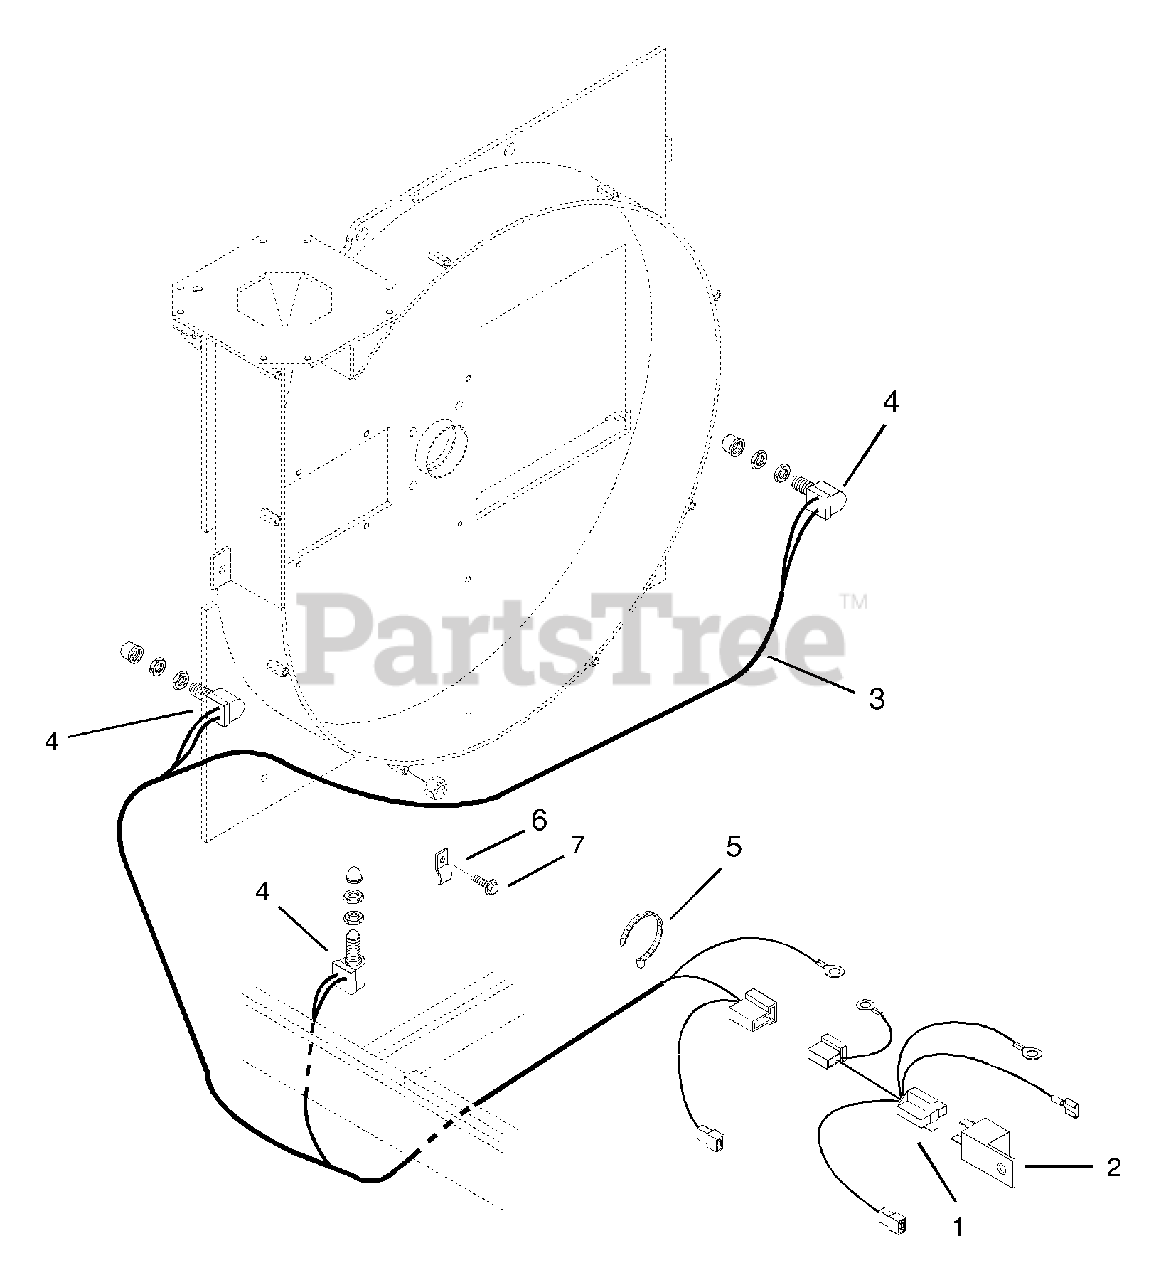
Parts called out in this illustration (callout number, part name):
1	Harness-Relay / Safety
1	Harness-Adapter Safety Switch
2	Relay
3	Harness-Wiring, Safety Switch
4	Safety Switch
5	Cable Tie
7	Screw-Tapping-Hex Washer Head .25-20 x .50
